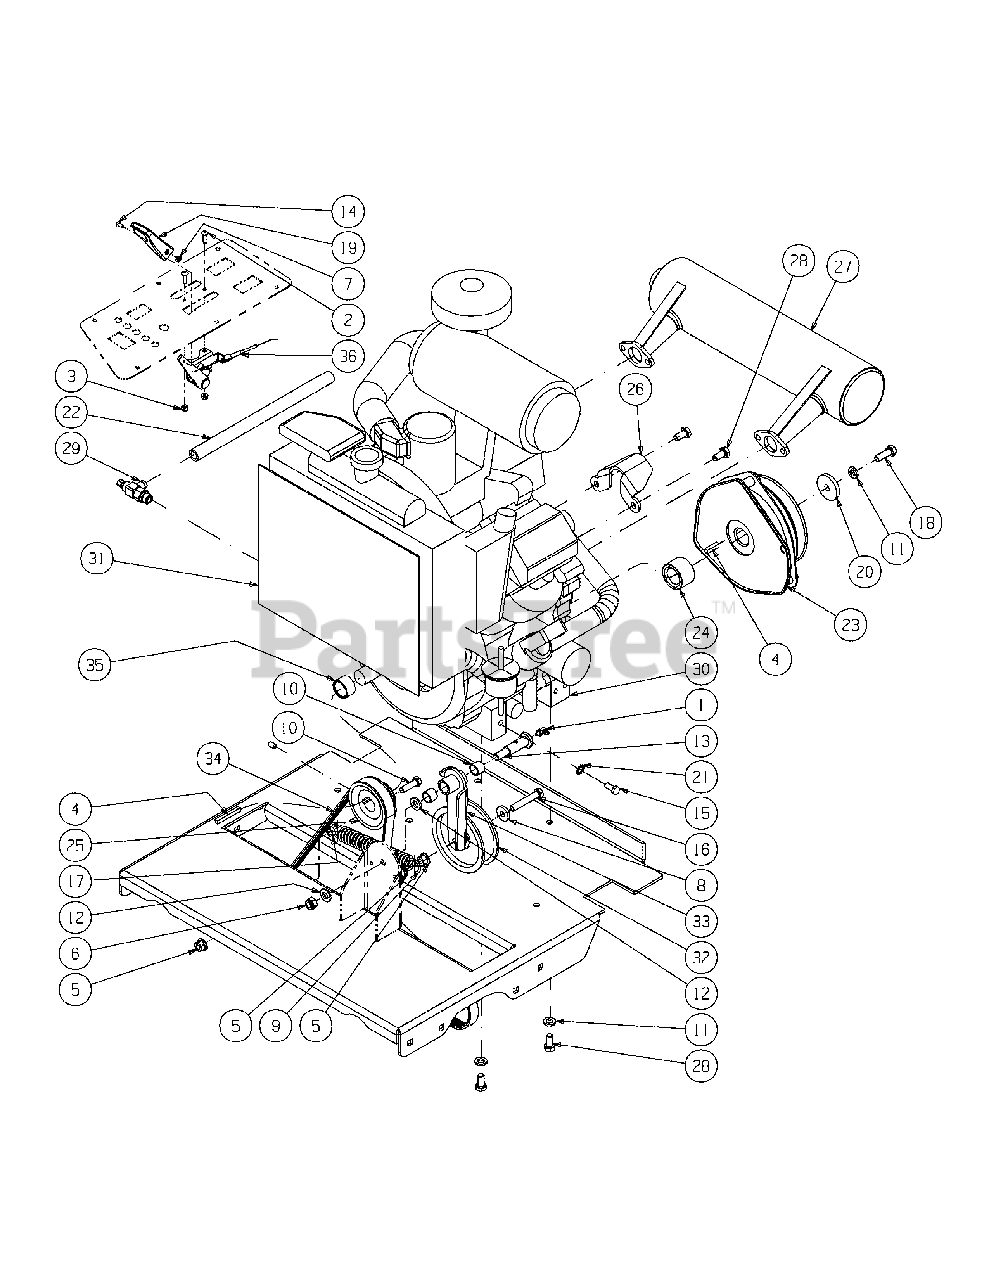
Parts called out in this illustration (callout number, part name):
1	Grease Fitting, 1/4-28 90 Degree
2	Round Hd. Machine Screw, 10-32 x 3/4
3	Lock Nut, Nylon Insert, 10-32
4	Key Stock, 1/4 x 1/4 x 2.00
5	Nut, 3/8-16, Hex Flange Lock
6	Nut, 7/16-14, Nylock
7	Nut Washer, W/Star, 8-32
8	Washer, 3/8
9	Extension Spring, 1.0 OD x 5.00
10	Hex Cap Screw, 3/8-16 x 1.25
11	Lock Washer, 7/16
12	Washer, .469 ID x .875 OD x .105
13	Shoulder Screw, 7/16-14
14	Machine Screw, 8-32, .375
15	HHCS, M10 x 1.25, 20mm
16	HHCS, 3/8-16 x 2.25
17	Jam Nut, 3/8-16
18	HHCS, M10 x 1.5, 30mm
19	Control Throttle Knob
20	Flat Washer, 7/16 ID x 1.75 OD x .25
21	Washer, 3/8 ID, External Tooth
22	Oil Drain Extension Hose
23	Clutch Brake
24	Spacer, 1.75 OD x 1.135 ID x 1.125
25	Pulley, 3.05 OD x 1.0 Bore
26	Clutch Retainer Bracket
27	Muffler, 29HP Horizontal, Kawasaki
28	Hex Head Cap Screw, M10 x 1.5, 20mm
29	Oil Valve
30	29HP Digital Fuel Injection Engine, Kawasaki
31	Screen, Kawasaki 29HP Radiator
32	Idler Pulley, 3.5 OD
33	Idler Arm Assembly
33	Bearing
34	V Belt
35	Spacer, 1.25 OD x 1.01 ID x .731
36	Throttle Cable, 42.0
